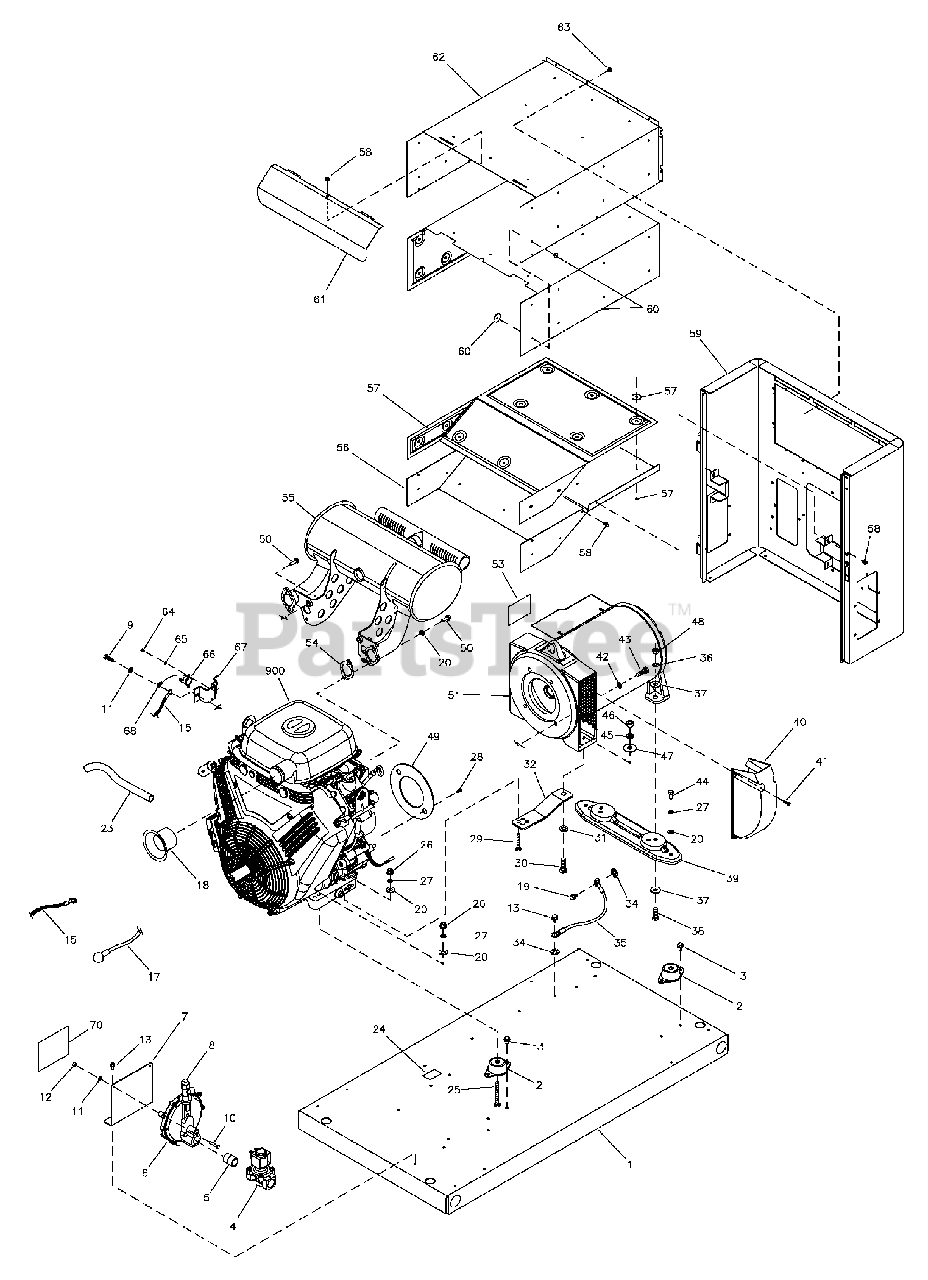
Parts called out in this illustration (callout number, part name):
1	BASE
2	MOUNT, Vibration
4	SOLENOID, Gas Fuel
6	REGULATOR, NG/LPG
7	BRACKET
9	* CAPSCREW, Hex Head, M6-1 x 16
10	* CAPSCREW, Hex Head, M6-1 x 30
11	* WASHER, Lock, 1/4
12	* NUT, M6-1
13	BOLT
15	CABLE, Battery, Black
17	CABLE, Battery, Red
19	* CAPSCREW, Hex Head, M6-1 x 12
20	* WASHER, Flat, 5/16-M8
23	HOSE, Oil Drain
24	DECAL
25	* CAPSCREW, Hex Head, 5/16-18 x 2-1/2
26	* NUT, 5/16-18
27	* WASHER, Lock, 5/16-M8
28	* CAPSCREW, Hex Head, SEMS, 5/16-24 x 3/4
29	* CAPSCREW, Hex Head, 5/16-18 x 2
30	* CAPSCREW, Hex Head, M12 - 1-3/4 x 35
31	* WASHER, M12
32	SUPPORT, Engine
34	* WASHER, Shakeproof, EXT, M6-1/4
36	* WASHER, Lock, M10
37	* WASHER, Flat, M10
38	* CAPSCREW, Hex Head, M10- 1-1/2 x 30
39	SUPPORT, Alternator
41	* SCREW, Phillips Head, M5-0.8 x 20
42	* WASHER, Lock, 3/8
43	* CAPSCREW, Hex Head, 3/8-16 x 1-1/4
44	* CAPSCREW, Hex Head, 5/16-18 x 3/4
45	* WASHER, Lock, M12
46	* NUT, Hex, M12 - 1-3/4
47	* WASHER, Flat, M12
48	* NUT, M10 - 1-1/2
50	* CAPSCREW, Hex Head, M8 - 1-1/4 x 25
51	ALTERNATOR, Complete
53	DECAL
59	BULKHEAD, Alternator
62	BOX, Muffler Top
64	* SCREW, Phillips Head, 4-40 x 3/16
65	* WASHER, Lock, #4
66	SWITCH, Temp
67	PLATE, Temp Switch
900	** ENGINE
